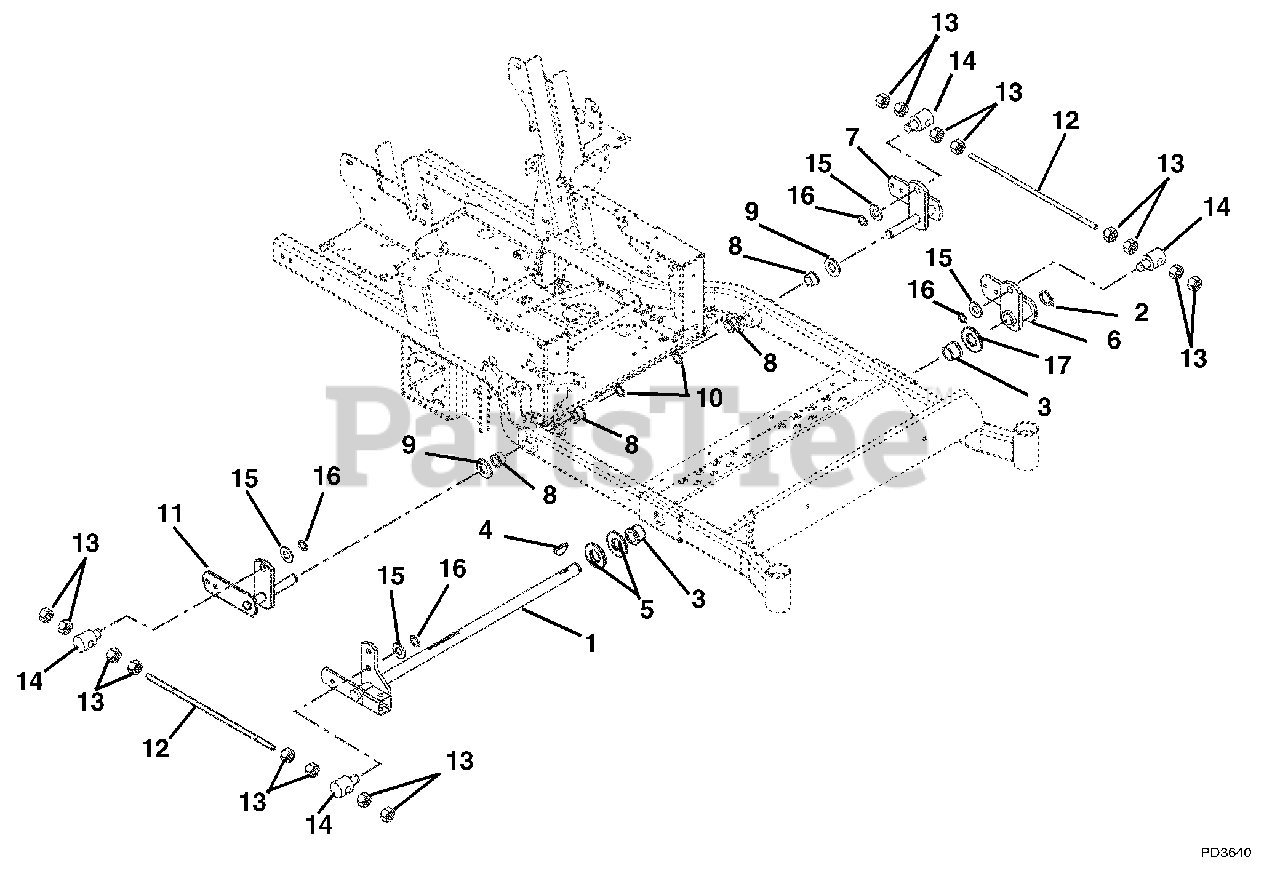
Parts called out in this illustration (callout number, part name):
1	Weldment, Lift Arm
2	Ring-Retaining-External 1.00 x .078
3	Bushing-Flange-Nylon 1.020 x 1.385 x .75 x 1.75
4	Key-Woodruff .25 x 1.00
5	Washer-Flat-Steel 1.063 x 2.00 x .134
6	Weldment, Lift Arm-Front
7	Weldment, Lift Arm-Shaft-Left Hand
8	Bushing-Flange-Nylon .762 x 1.0 x .580 x 1.48
9	Washer-Hardened-Steel .758 x 1.23 x .031
10	Ring-Retaining-External .689 x .077
11	Weldment, Lift Arm Shaft-Right Hand
12	Rod-Lift Assist
13	Nut-Jam .50-13
14	Pivot-Mower Lift
15	Washer-Flat-Steel .630 x 1.005 x .062
16	Ring-Retaining-External .625 x .05
17	Washer-Hardened-Thrust 1.00 x 1.55 x .03
